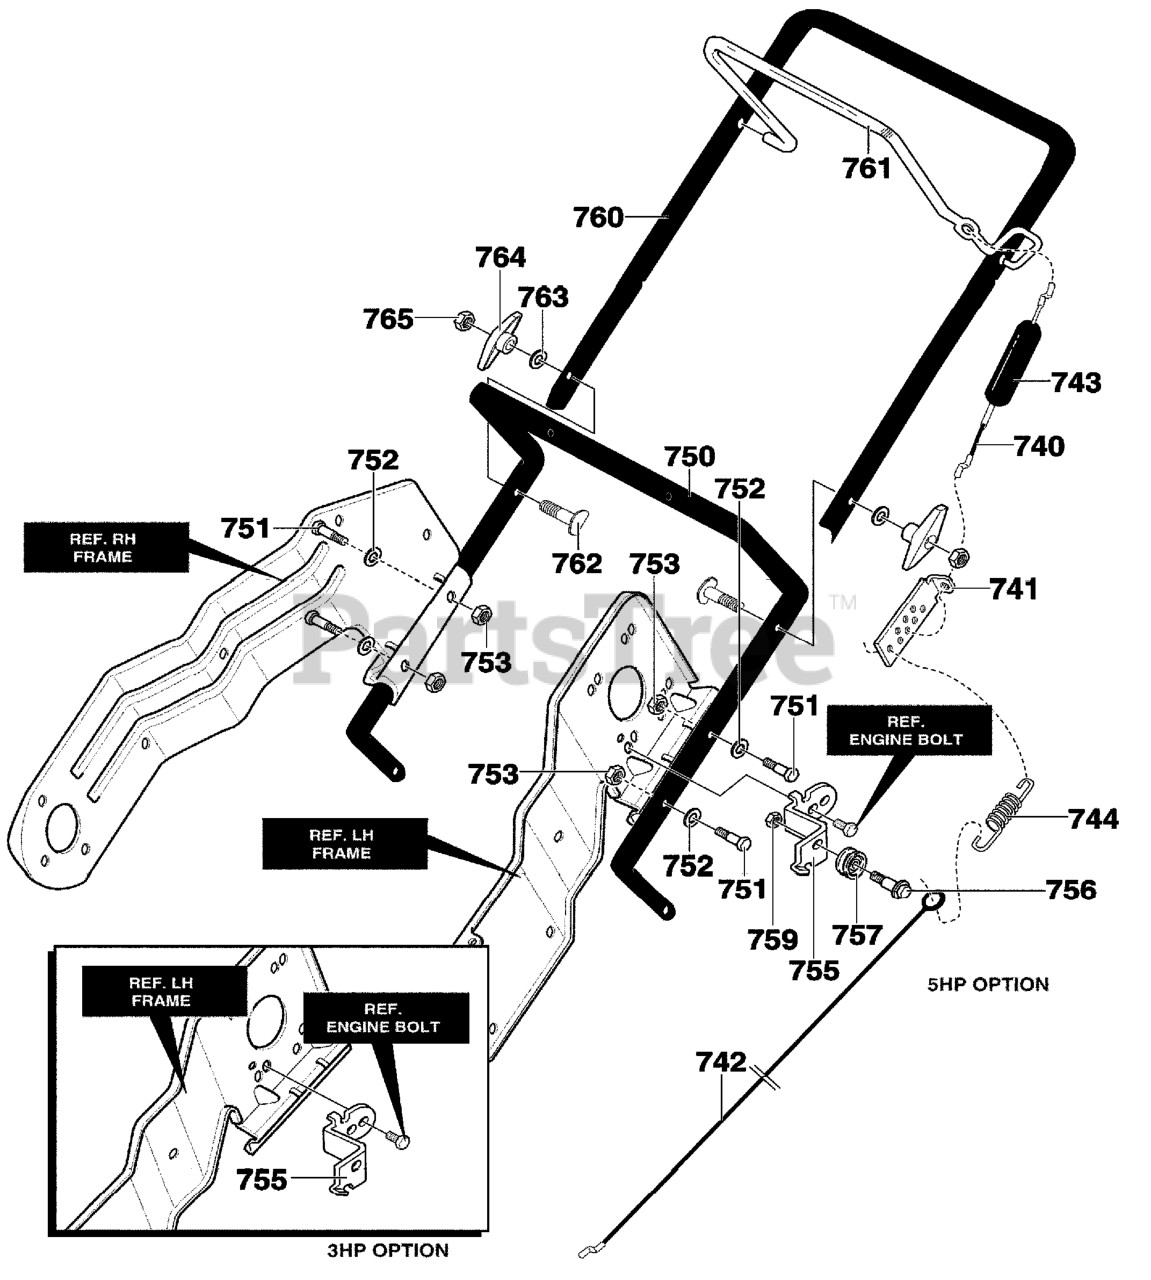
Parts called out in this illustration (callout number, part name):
740	CABLE, UPPER
741	BRACKET, CABLE ADJ
742	CABLE, LOWER CONTROL
743	BOOT, CLUTCH SPRING
744	SPRING, EXTENSION
750	HANDLE, LOWER
751	SCREW, 1/4-20X1.25
752	WASHER, FLAT
753	NUT, 1/4-20
755	BRACKET, CABLE
757	PULLEY, NYLON
759	NUT, 1/4-20
760	UPPER HANDLE
761	BAIL, CONTROL
762	BOLT, 5/16-18X2.00
763	WASHER, FORM
764	T-KNOB
765	NUT, 5/16-18
